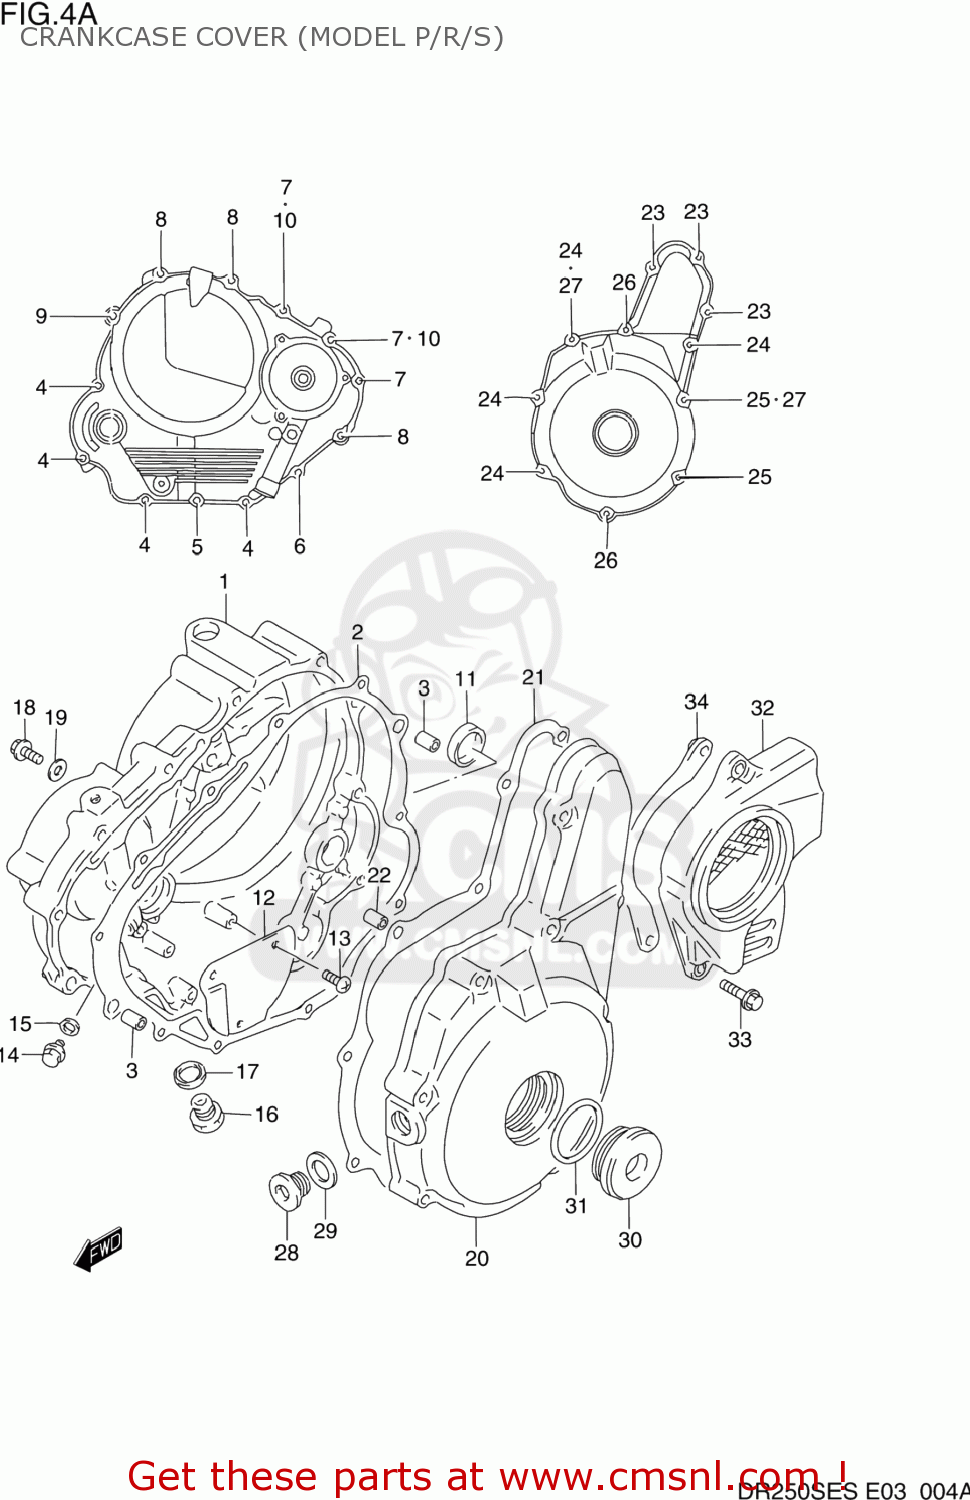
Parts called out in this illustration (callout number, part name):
1	COVER,CLUTCH
2	GASKET,CLUTCH COVER (NAS)
3	PIN
4	SCREW
5	BOLT,G/S SWITC
6	BOLT
7	BOLT
8	BOLT
9	BOLT
10	GASKET(5.8X13X1.2) (NAS)
11	PLUG,CLUTCH COVER KICK
12	SEPARATOR,OIL RETURN
13	SCREW
14	BOLT(6X8)
15	GASKET(6.2X11X1).2 (NAS)
16	PLUG(10X6.8)
17	GASKET(10X14X3.6) (NAS)
18	SCREW (6X10)
19	GASKET(5.8X13X1.2) (NAS)
20	COVER,MAGNETO
21	GASKET,MAGNETO COVER (NAS)
22	PIN
23	SCREW
24	BOLT
25	BOLT
26	BOLT
27	GASKET(5.8X13X1.2) (NAS)
28	PLUG,14X12
29	GASKET(14X19.2X2) (NAS)
30	PLUG(SILVER)
31	O RING(D:3.1,ID:32.7)
32	COVER,ENGINE SPROCKET
33	SCREW
34	PLATE,FR CHAIN GUIDE
